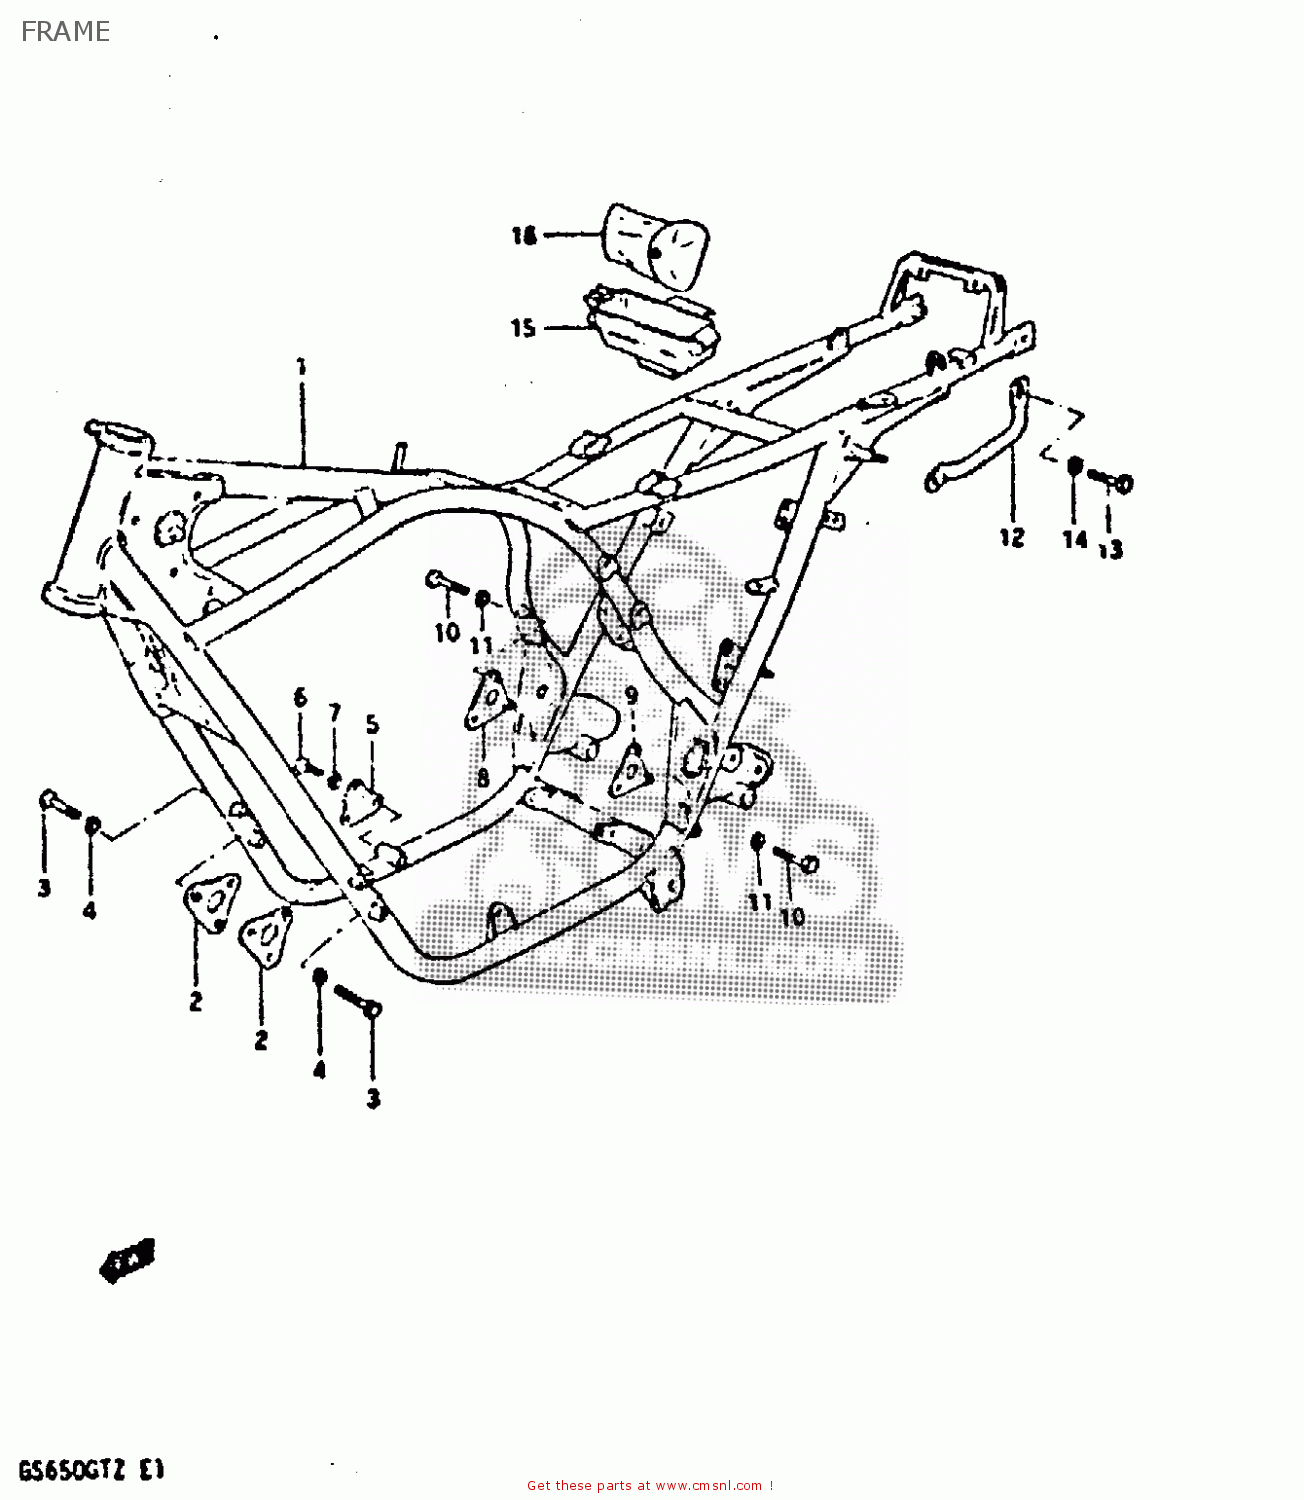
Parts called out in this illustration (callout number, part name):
1	FRAME
2	PLATE,ENGINE MOUNTING NO
3	BOLT
4	LOCK WASHER
5	BOLT,CRANKCASE ADJUST
6	BOLT
7	LOCK WASHER
8	PLATE,ENGINE MOUNTING NO
9	PLATE,ENGINE MOUNTING
10	BOLT
11	LOCK WASHER
12	GRIP,FRAME HANDLE
13	BOLT
14	WASHER
15	HOLDER,TOOL
16	TOOL SET
